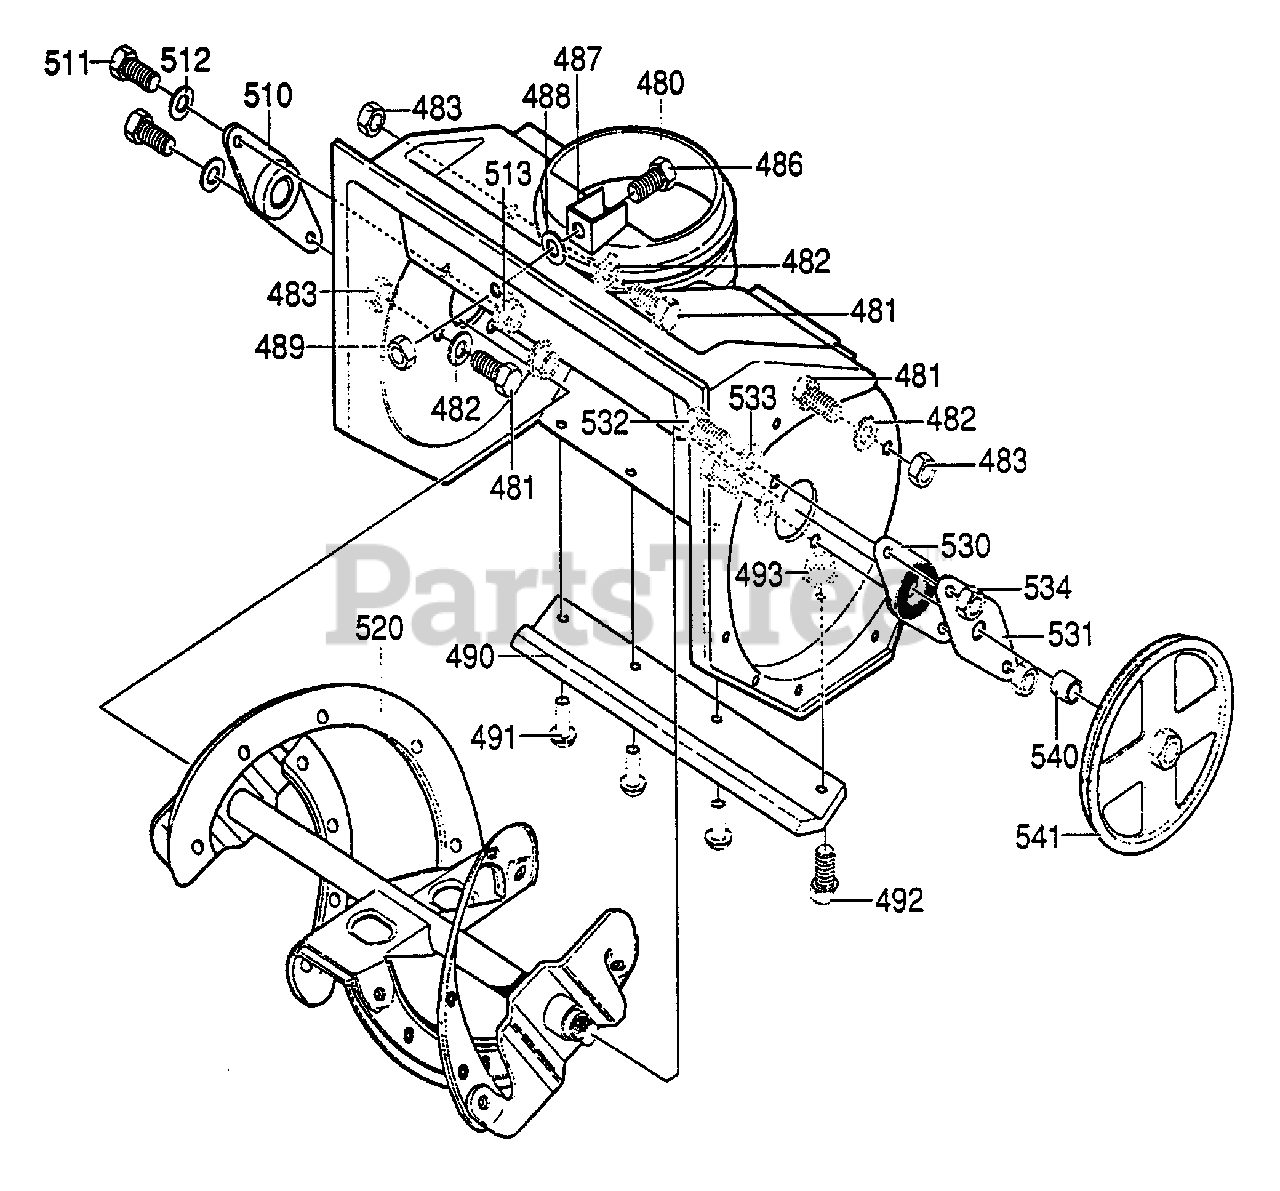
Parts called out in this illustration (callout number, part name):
480	HOUSING, RING & AUGER
481	SCREW, 1/4-20 X .75
482	FLATWASHER .281 X .63 X .065
483	NUT, 1/4-20
486	SCREW, 1/4-20 X .63
487	BRACKET, STOP
488	FLATWASHER .333 X .87 X .119
489	NUT, 1/4-20
490	BLADE, SCRAPER
492	SCREW, 1/4-20 X .75
493	NUT, 1/4-20
510	BRNG, FL
511	SCREW, 1/4-20 X .88
512	FLATWASHER .281 X .63 X .065
513	NUT, 1/4-20
520	AUGER, ASSY COMP
530	BRNG & PLATE, ASSY
531	RETAINER, BRNG
532	SCREW, 1/4-20 X .62
533	FLATWASHER .281 X .63 X .065
534	NUT, 1/4-20
540	SPACER, SLEEVE
541	PULLEY, POLY 6"
